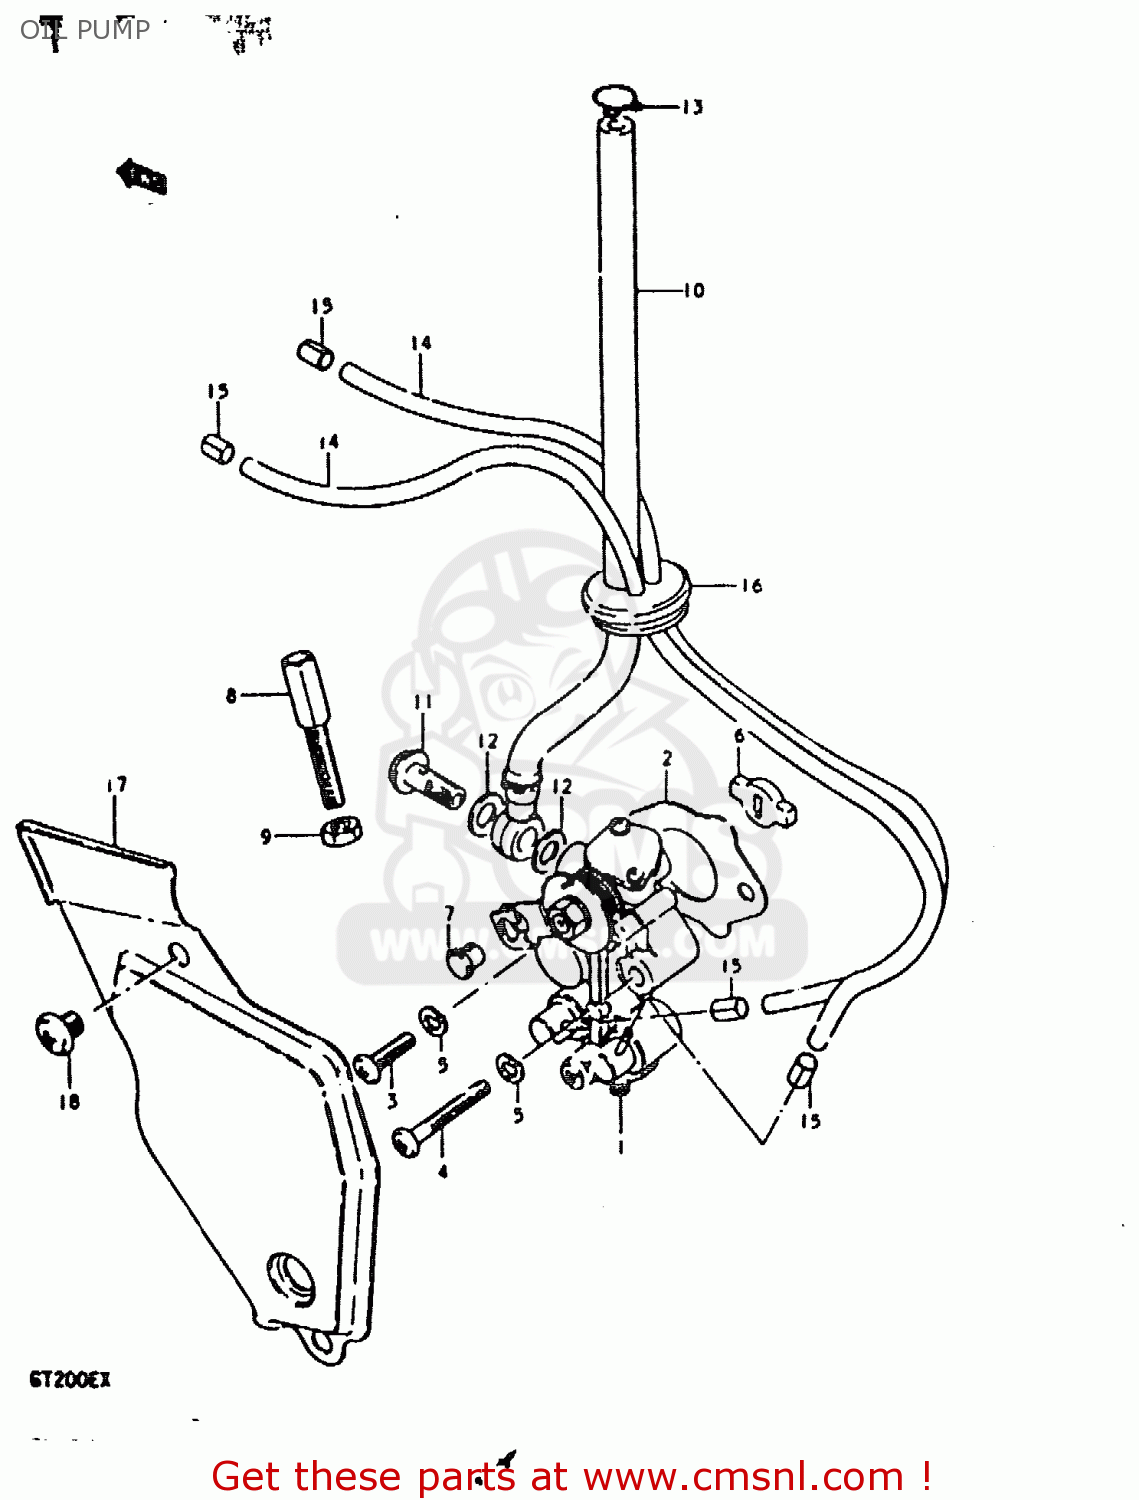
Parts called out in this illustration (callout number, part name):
1	PUMP ASSY, OIL
2	GASKET,OIL PUMP (NAS)
3	SCREW
4	SCREW
5	LOCK WASHER
6	PIECE,OIL PUMP DRIVE
7	TERMINAL,CABLE
8	BOLT
9	NUT
10	HOSE,OIL NO.1
11	UNION BOLT
12	GASKET(6.2X11X1).2 (NAS)
13	CLIP
14	HOSE, OIL NO.2
15	CLIP
16	GROMMET,OIL HOSE
17	CAP, INSPECTION
18	SCREW
